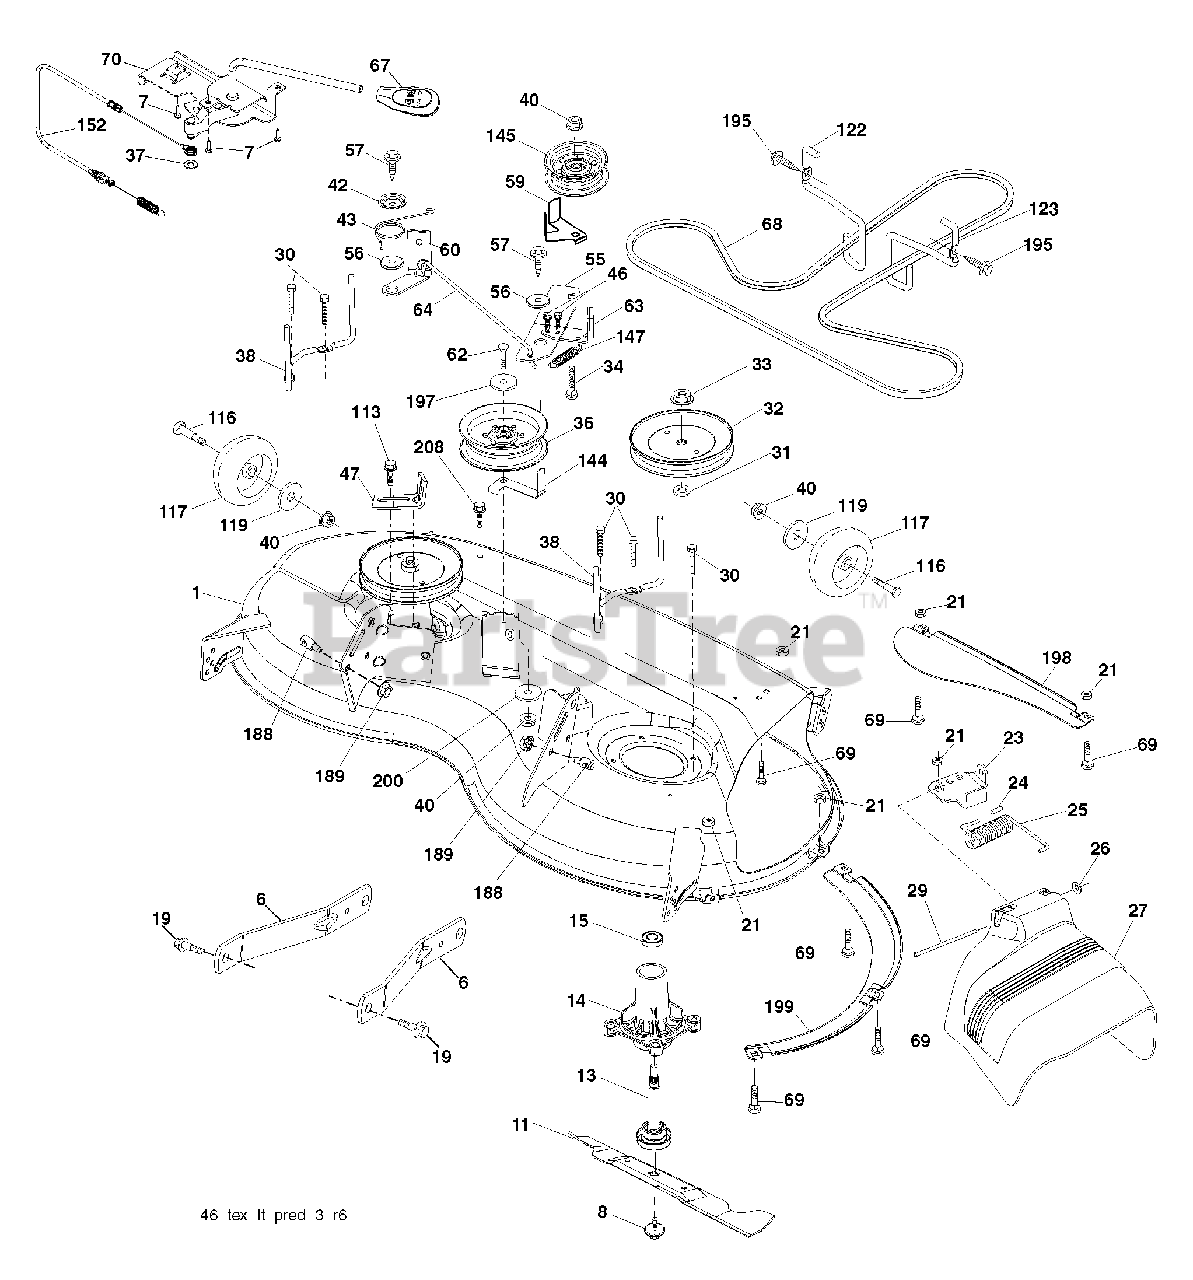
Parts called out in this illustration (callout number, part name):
2	Cover Mandrel RH
3	Cover Mandrel LH
6	Arm Suspension
7	Screw 10 x 3/4 Single Hex
8	Bolt/Washer asm 7/16-20 unf
11	Blade Mower
13	Shaft Assembly, Mandrel
14	Housing, Mandrel
15	Bearing, Ball, Mandrel
19	Bolt, Shoulder
21	Nut
23	Bracket, Deflector
24	Cap, Sleeve
25	Spring, Torsion, Deflector
26	Nut, Push
27	Shield, Deflector
29	Rod, Hinge
30	Screw Thdrol Rolling Wsh Hd
31	Washer, Spacer
32	Pulley, Mandrel
33	Nut, Toplock, Flanged
34	Bolt Carr Sh. 3/8-16 x 1-1/2 Gr.
36	Pulley, Idler, Flat
37	Washer 13/32 x 13/16 x 16 Ga.
38	Keeper Belt LH Mandrel
40	Nut, Lock Flg. 3/8-16 unc
42	Spring Trosion Brake
43	Spring Torsion Retainer
46	Screw
47	Bracket Clutch Cable
55	Arm, Idler
56	Spacer, Retainer
57	Screw Hexwsh Thd 3/8-16 x 1
59	Guard, Tuv Idler (94)
60	Arm Brake Mower
62	Bolt Fin Hex 3/8-16 x 2-1/4 Gr.
63	Arm Brake Mower
64	Linkage Brake
67	Handle, Clutch Cable
68	V-Belt
69	Bolt
70	Clutch Asm. Manual
113	Screw 5/16-18
116	Bolt, Shoulder
117	Wheel, Gauge
118	Nut, Crownlock 3/8-1
119	Washer 13/32 x 7/8 x 14 Ga.
122	Keeper Belt Eng. LH
123	Keeper Belt Eng. RH
144	Keeper Belt
145	Pulley Idler
147	Spring Return
152	Cable Clutch Manual w/Spr.
188	Stud Fastener
189	Nut Lock Hex Flange
195	Screw 3/8-16 x 3/4
196	Washer 13/32 x 2 x 10 Ga
197	Washer 13/32 x 13/16 x 12 Ga.
198	Baffle Center Front
199	Baffle Front RH
199	Mandrel Assembly
199	Replacement Mower, Complete
